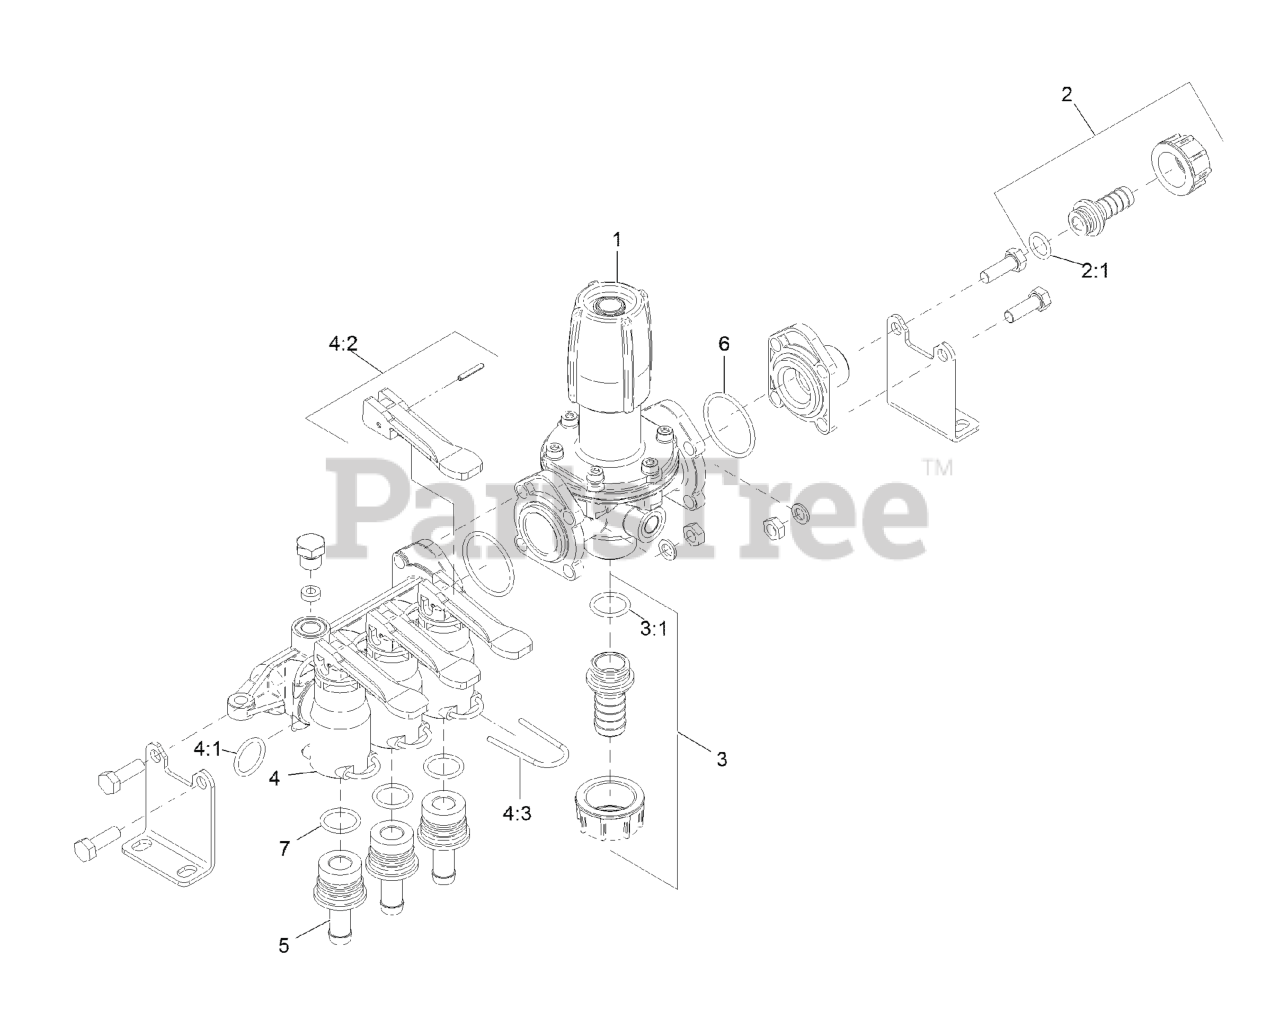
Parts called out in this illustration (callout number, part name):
1	REGULATOR
2	FLYNUT ASSEMBLY
2:1	O-RING KIT, REGULATOR INL
3	FLYNUT ASSEMBLY
3:1	O-RING KIT, REGULATOR OUT
4	VALVE ASSEMBLY W/ O-RING
4:1	O-RING KIT, VALVE INLET
4:2	LEVER AND PIN ASSEMBLY
4:3	WIREFORM RETAINER KIT
5	HOSE BARB
6	O-RING KIT, REGULATOR FLA
7	O-RING KIT, VALVE OUTLET
